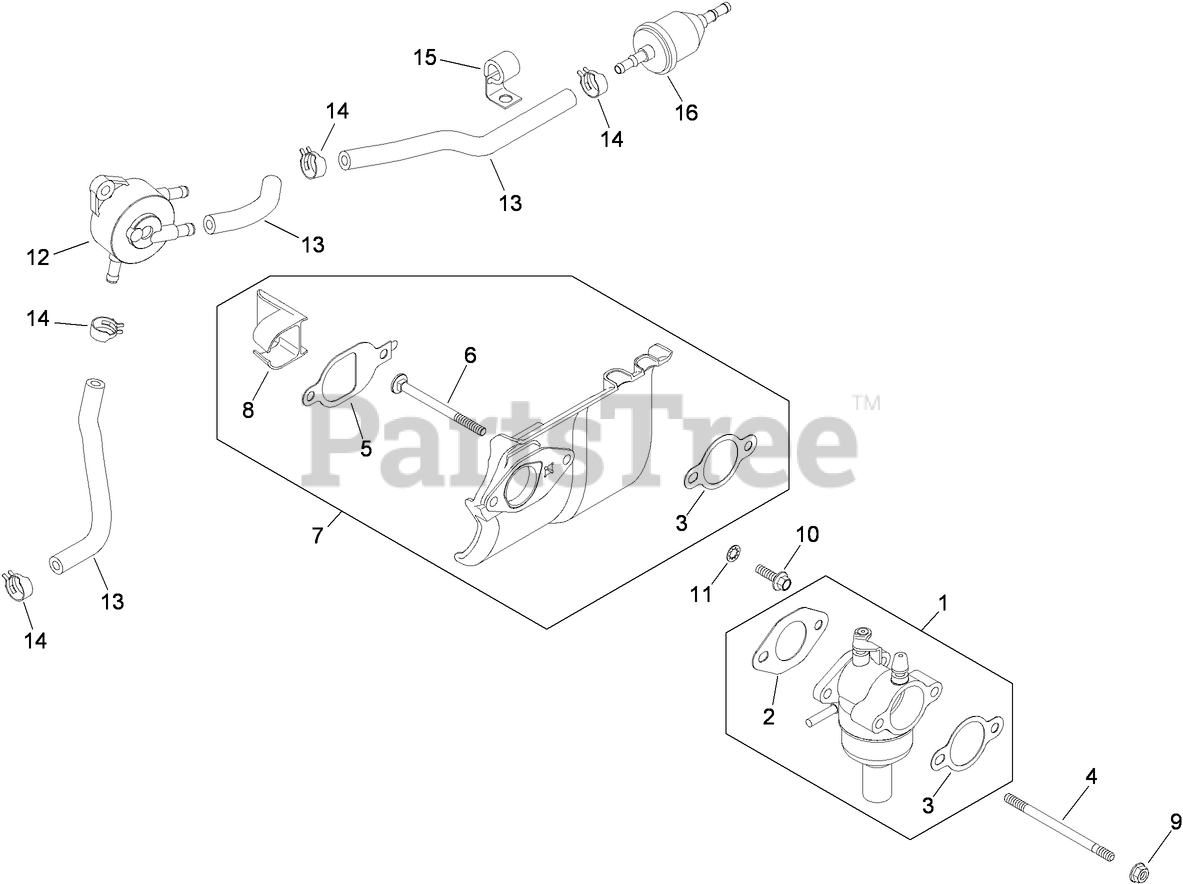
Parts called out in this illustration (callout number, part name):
1	CARBURETOR KIT (INCLUDES REF 10, 11) (S/W 12 755 109-S, 12 755 110-S, 12 757 02-S, 12 757 03-S, 12 757 33-S, 12 757 37-S, 20 755 07-S)
2	Gasket-Carburetor
3	Gasket-Base, Air Cleaner
4	Stud-Mounting, Carburetor (M6X1.0X100)
5	GASKET-DEFLECTOR, HEAT
6	STUD-CARBURETOR
7	HEAT DEFLECTOR KIT (INCLUDES REF 11, 14, 15, 20 332 01-S)
8	INSERT-PORT, INTAKE
9	NUT-FLANGE (M6X1.0)
10	Screw-Flange, Hex (M6x1.0x20)
11	Washer-Lock, Internal Tooth (1/4)
12	PUMP-FUEL
13	LINE-FUEL (24-CUT TO LENGTH)
14	CLAMP-HOSE, SPRING (1/2)
15	CLIP-CABLE
